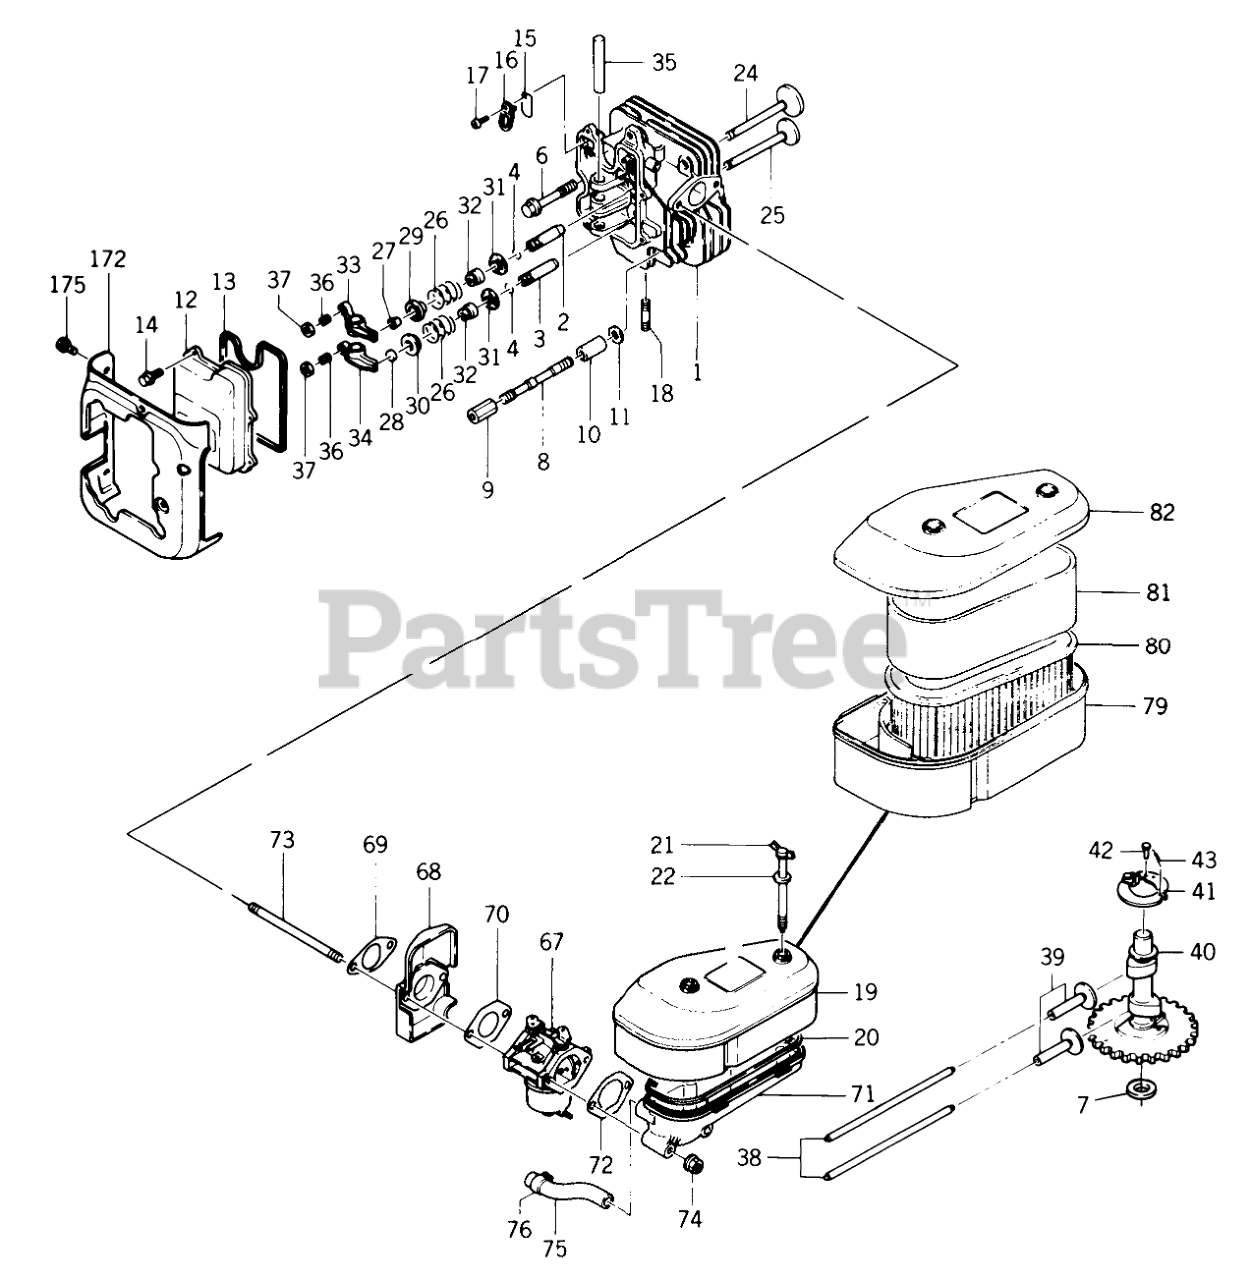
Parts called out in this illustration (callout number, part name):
1	CYLINDER HEAD
2	GUIDE-VALVE(IN)
3	GUIDE-VALVE (EX)
4	RING-SNAP
6	BOLT-HEAD
7	SHIM 1.54
7	SHIM-1.575
7	SHIM-1.61
7	SHIM-1.645
7	SHIM 1.68
7	SHIM-1.715
7	SHIM-1.75
7	SHIM-1.785
7	SHIM-1.82
7	SHIM-1.855
7	SHIM-1.89
10	COLLAR
11	WASHER
12	CASE ROCKER
13	GASKET ROCKER CASE
14	Bolt
15	VALVE
16	PLATE
17	SCREW
19	Air Filter Assembly
20	GASKET AIR FILTER
22	WASHER
24	VALVE INTAKE
25	VALVE EXHAUST
26	Valve Spring
27	COLLET VALVE
28	CAP VALVE
29	RETAINER SPRING
30	RETAINER SPRING
31	SEAT SPRING
32	SEAL-OIL
33	ARM ROCKER
34	ARM ROCKER
35	SHAFT ROCKER
36	SCREW
38	ROD PUSH
39	TAPPET
40	SHAFT-CAM
41	DECOMPRESSOR
43	SPRING
67	Carburetor Assembly See Section 10-5 for complete breakdown
68	INSULATOR
69	GASKET
70	GASKET
71	PIPE INTAKE
72	Gasket
74	NUT
80	ELEMENT AIR FILTER
81	WRAPPER AIR FILTER
82	CAP AIR FILTER
172	SHROUD
175	Bolt 6 x 12
